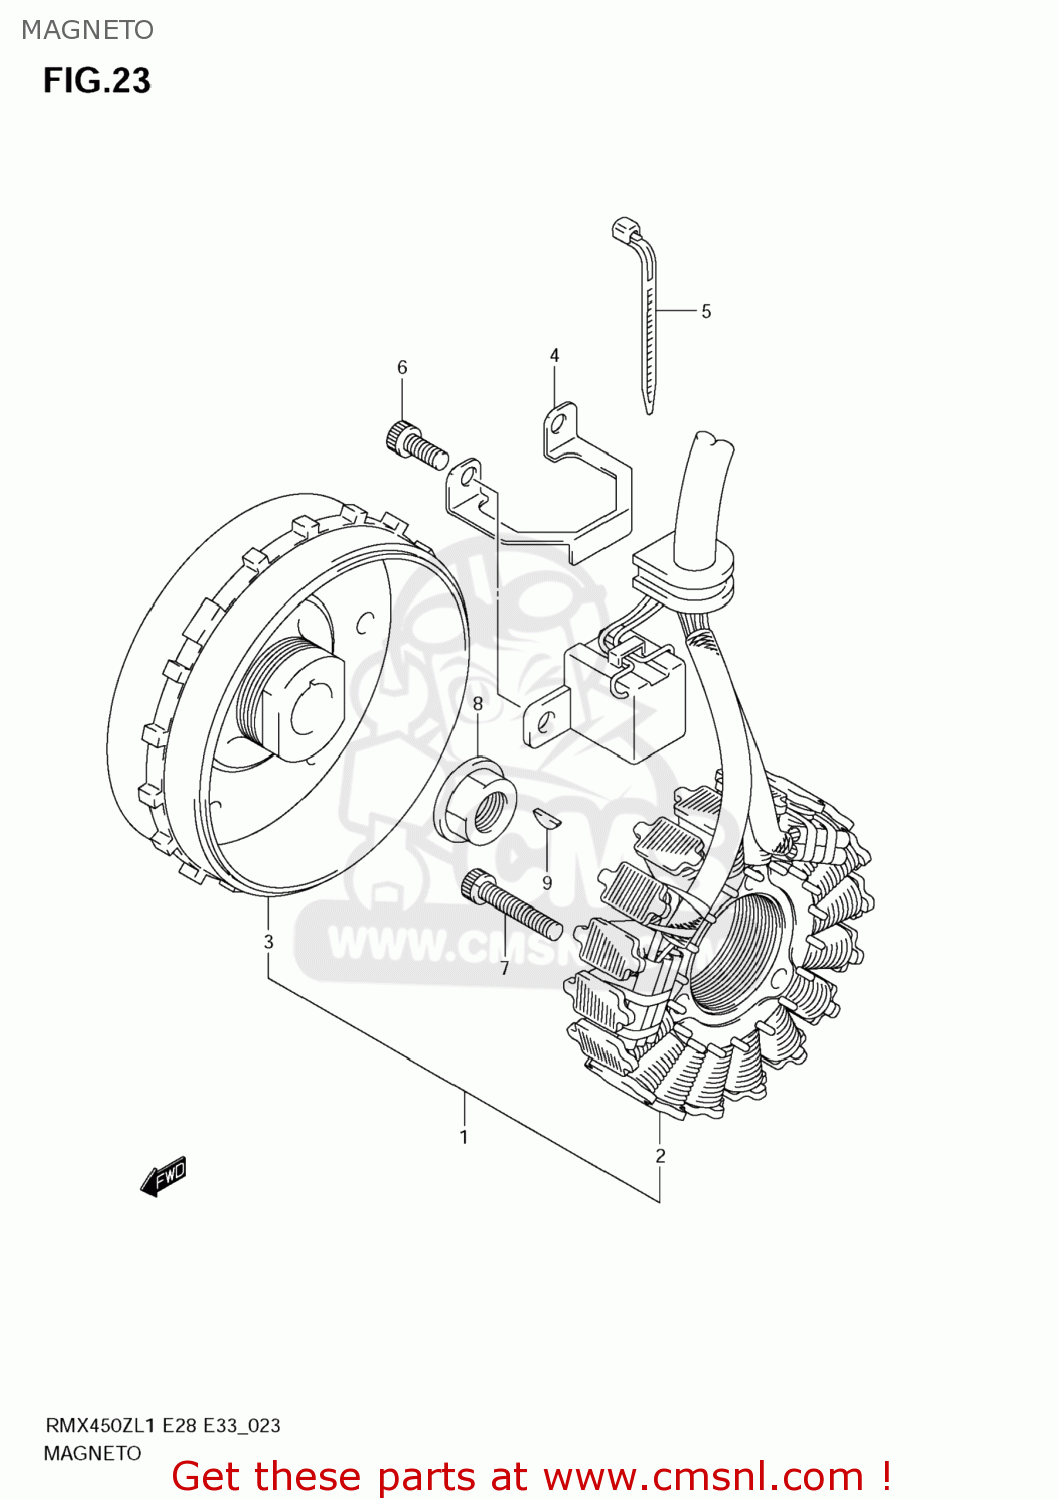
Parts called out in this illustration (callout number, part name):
1	MAGNETO ASSY
2	STARTER ASSY
3	ROTOR ASSY
4	CLAMP,MAGNETO LEAD
5	CLAMP(L:165)
6	BOLT
7	BOLT
8	NUT
9	KEY
